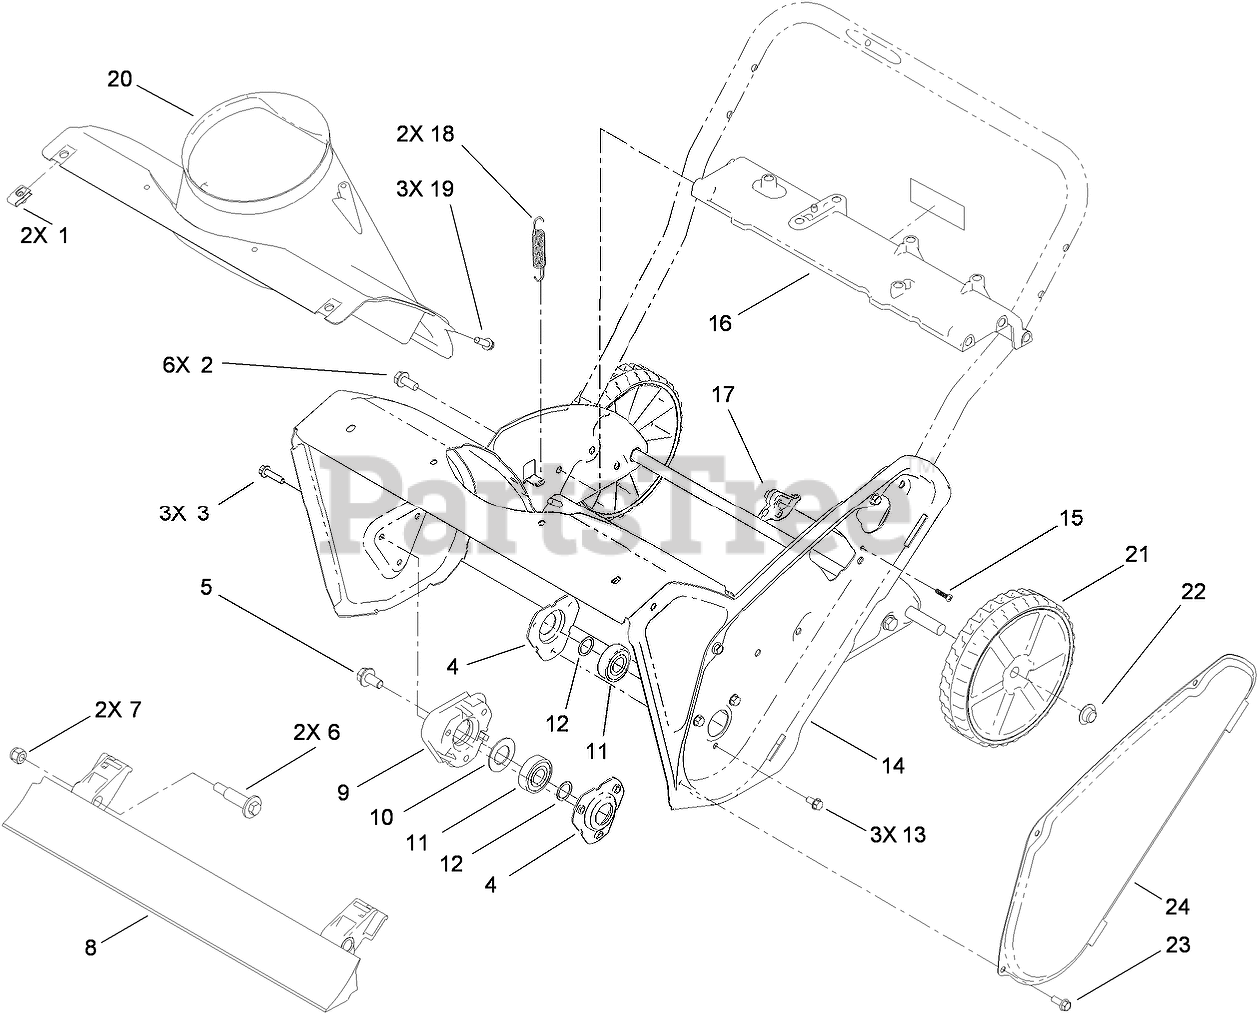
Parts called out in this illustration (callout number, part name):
2	SCREW-HWHTF
3	SCREW-HWHTF
4	FLANGE-BEARING
5	SCREW-HWH
6	BOLT-WHEEL
7	NUT-LOCK, NI
8	BLADE-SCRAPER
9	SPACER-BEARING, RH
10	WASHER-RUBBER
11	BEARING-BALL
12	WASHER-THRUST
13	SCREW-HWH
14	HOUSING-AUGER
15	SCREW-PPH
16	BRACE-FRAME
17	GUIDE-CABLE, CLUTCH
18	SPRING-EXTENSION
19	SCREW-HWH
20	CHUTE-LOWER
21	WHEEL ASM
22	NUT-PUSH
23	SCREW-HWH
24	COVER-BELT
